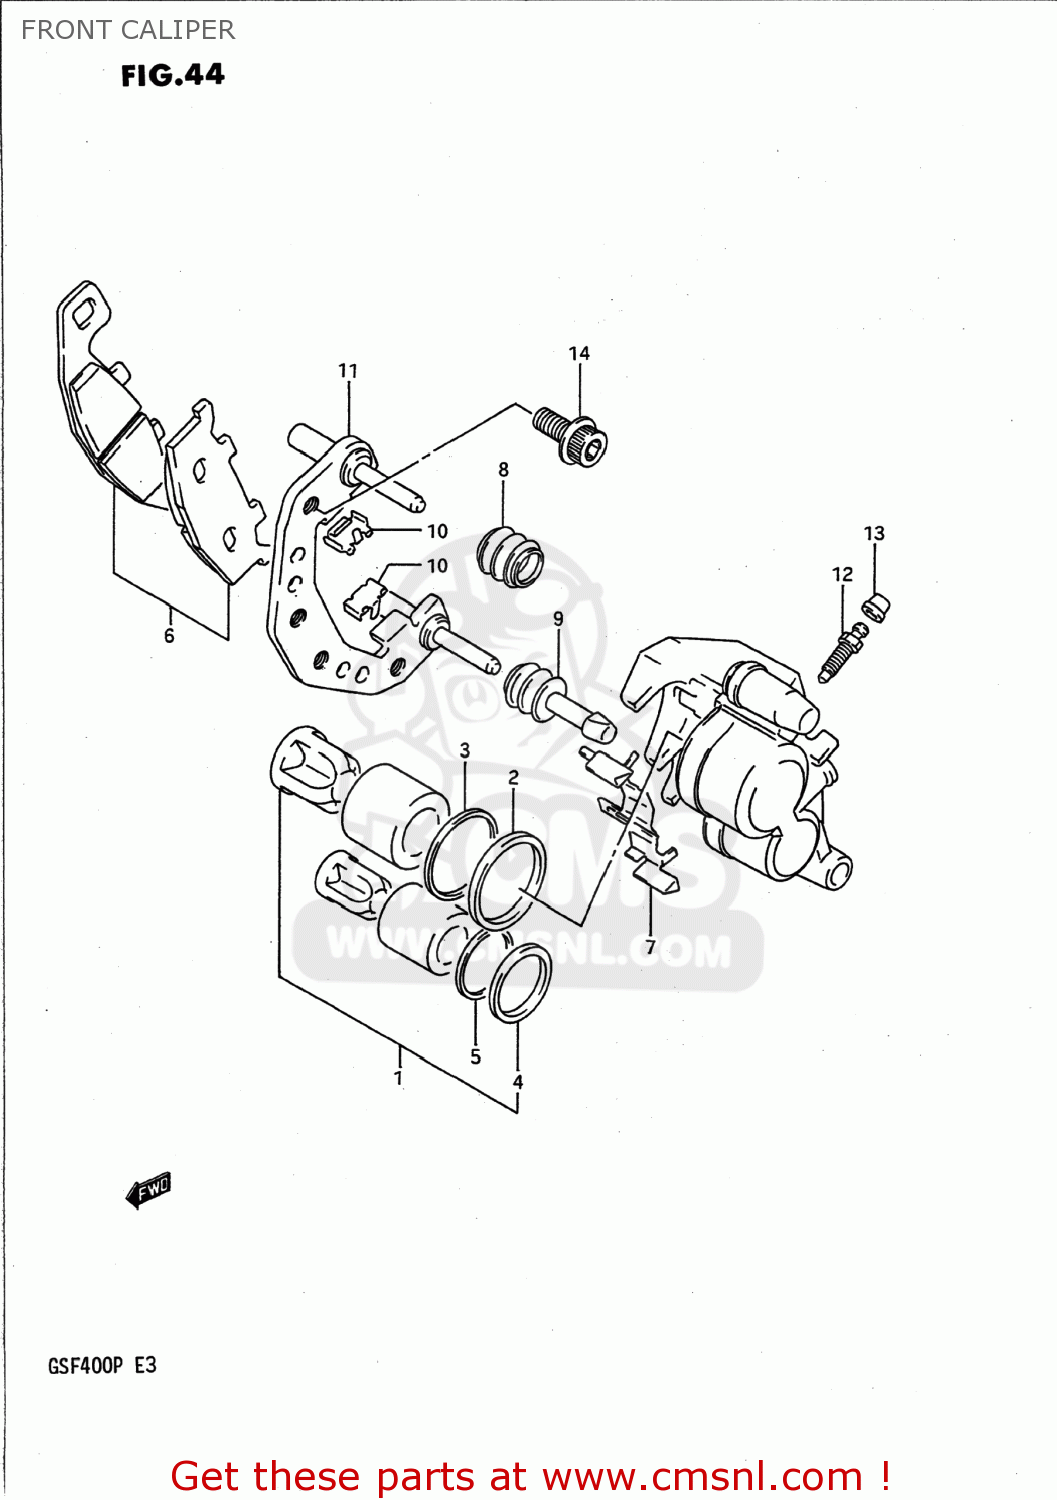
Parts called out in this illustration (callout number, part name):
1	PISTON SET
2	SEAL,PISTON
3	SEAL,WIPER
4	SEAL,PISTON
5	SEAL,WIPER
6	PAD SET (NAS)
7	SPRING,PAD
8	BOOT,AXLE
9	INSULATOR,AXLE
10	GUIDE,PAD
11	CARRIER,CALIPER
12	BLEEDER
13	CAP,BREATHER
14	BOLT
